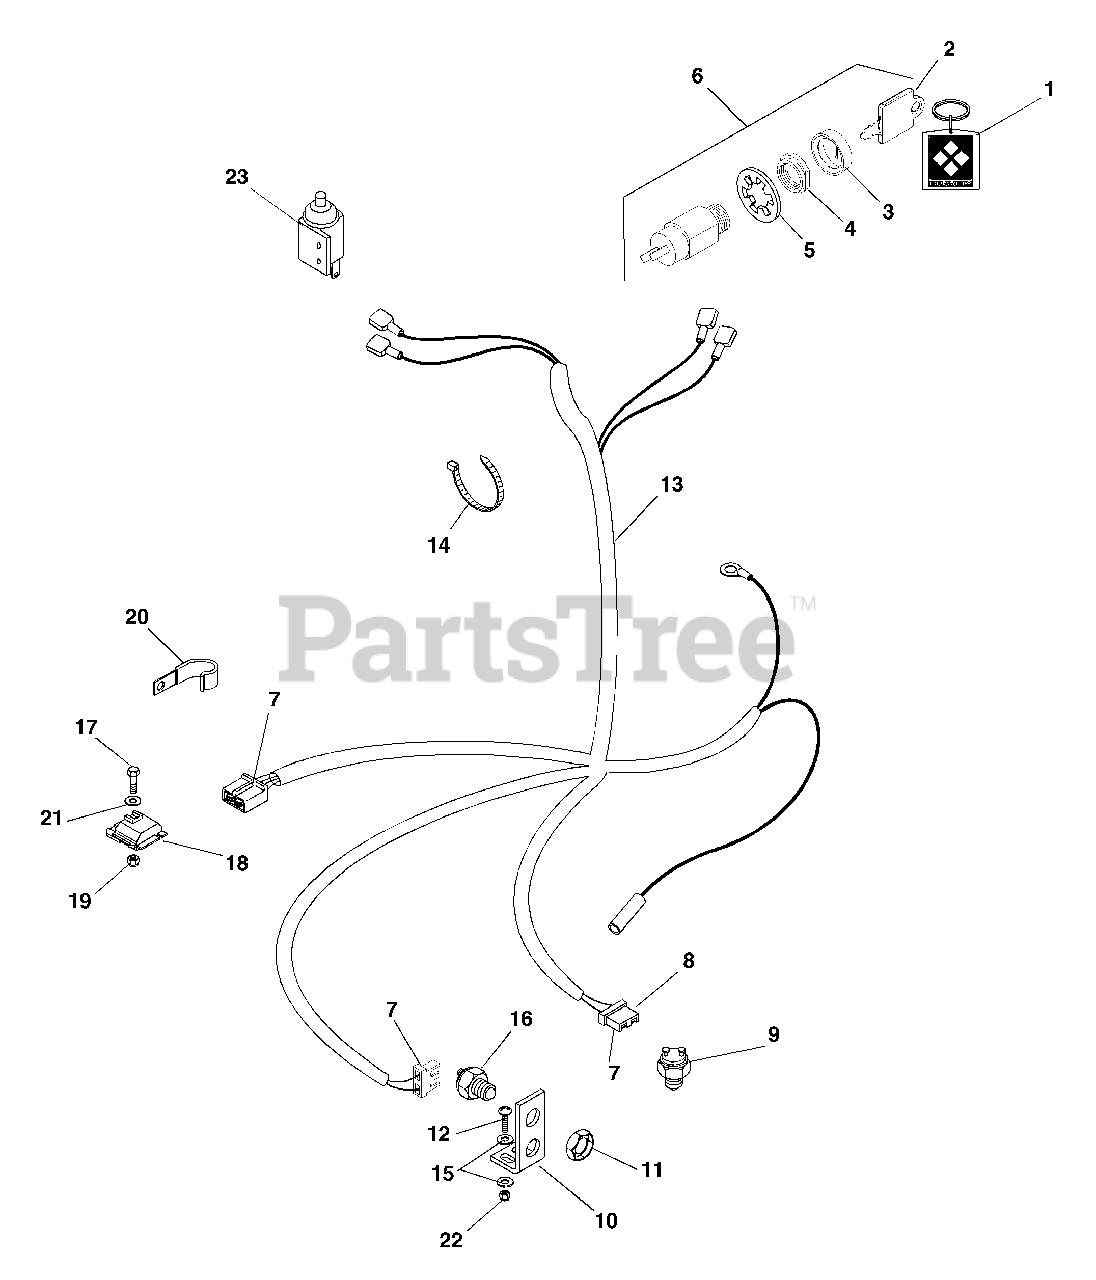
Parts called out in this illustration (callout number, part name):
1	KEY CHAIN
2	KEY -W/CAP
3	CAP - IGNITION SWITCH
4	NUT-PANEL .625-32 GRECO
5	WSHR-LK-INT .625X.045 YWZC
6	KEY SWITCH ASSEMBLY
7	TERMINAL
8	CONN,2-WIRE SWITCH
9	SWITCH, NEUTRAL START N.C.
10	BRKT,INTERLOCK SWITCH
11	NUT-STAMPED .56-18
12	@SCR-MCH 10-24X.75 HWH YWZC
13	WIRE HARNESS, PRO RECOIL
14	TIE WRAP, BLACK LG 7.31
15	@WSHR-FL-STL.219X.50X.049 YWZC
16	SWITCH-NEUTRAL START N.O.
17	@BLT-HEX .25-20X.75 GR5 YWZC
18	MODULE,INTERLOCK,ELEC, 1601
19	@NUT-LK-CTR .25-20 YWZC
21	WSHR-FL-STL.344X.688X.065PL
22	@NUT-LK-NYL 10-24 W/INSRT YWZC
23	SWITCH-SINGLE POLE N.O.W/COVER
